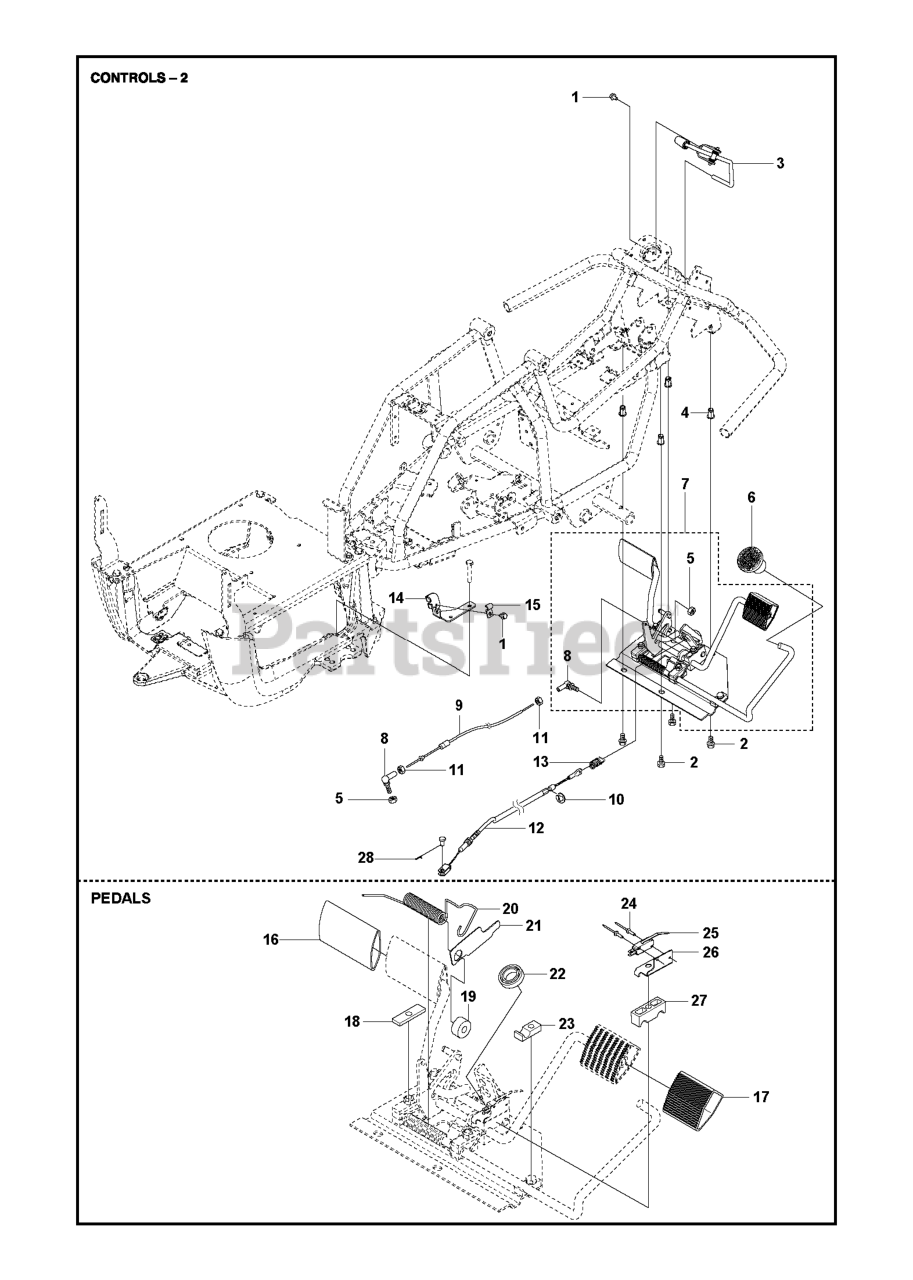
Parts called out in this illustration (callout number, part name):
3	LOCKING LEVER
6	KNOB, THREADED
8	CONNECTOR, BALL JOINT
9	CONTROL CABLE
11	LOCKNUT M5
12	BRAKE WIRE
16	PEDAL RUBBER L = 102MM
17	PEDAL RUBBER
22	BALL BEARING 6002-2RS1
25	MICRO SWITCH
27	PEDAL SHAFT CLAMP
28	Clevis Pin
